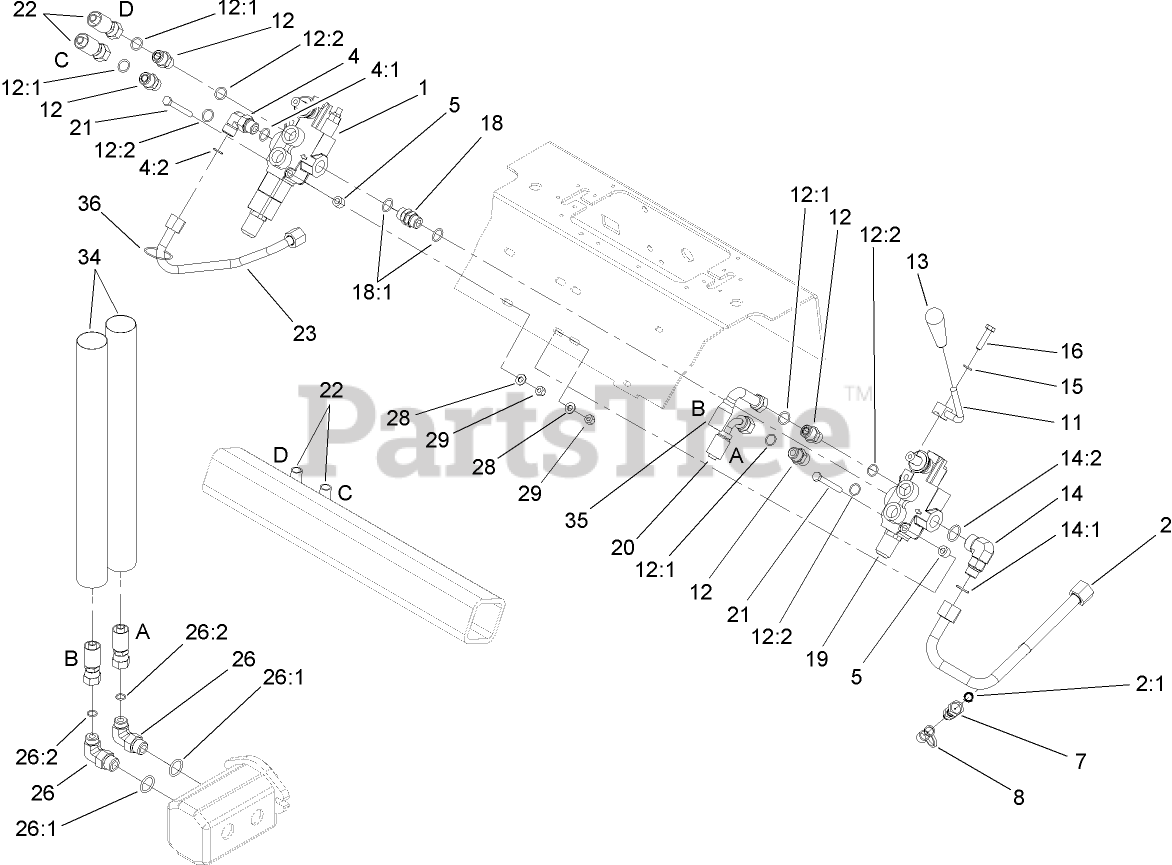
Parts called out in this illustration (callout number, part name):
1	VALVE-HYD, AUXILIARY
2	HYD TUBE ASM
2:1	O-RING
4	FITTING-ELBOW-90 DEG
4:1	O-RING
4:2	O-RING
5	SPACER
7	NIPPLE-TEST
8	CAP-DUST
11	LEVER-CONTROL
12	FITTING-STRAIGHT
12:1	O-RING
12:2	O-RING
13	KNOB-TAPERED
14	Fitting-Elbow, 90 DEG
14:1	O-RING
14:2	O-RING
15	WASHER-LOCK
16	SCREW-HH
18	FITTING-THREAD, STRAIGHT
18:1	O-RING
19	VALVE-SELECTOR, HYD
20	HOSE-HYD
21	SCREW-HH
22	HOSE-HYD
23	TUBE-HYD
26	FITTING-ELBOW 90
26:1	O-RING
26:2	O-RING
28	WASHER-PLAIN
29	NUT-LOCK, NI
34	SLEEVE-GUARD, HOSE
35	HOSE-HYD
36	TIE-CABLE
